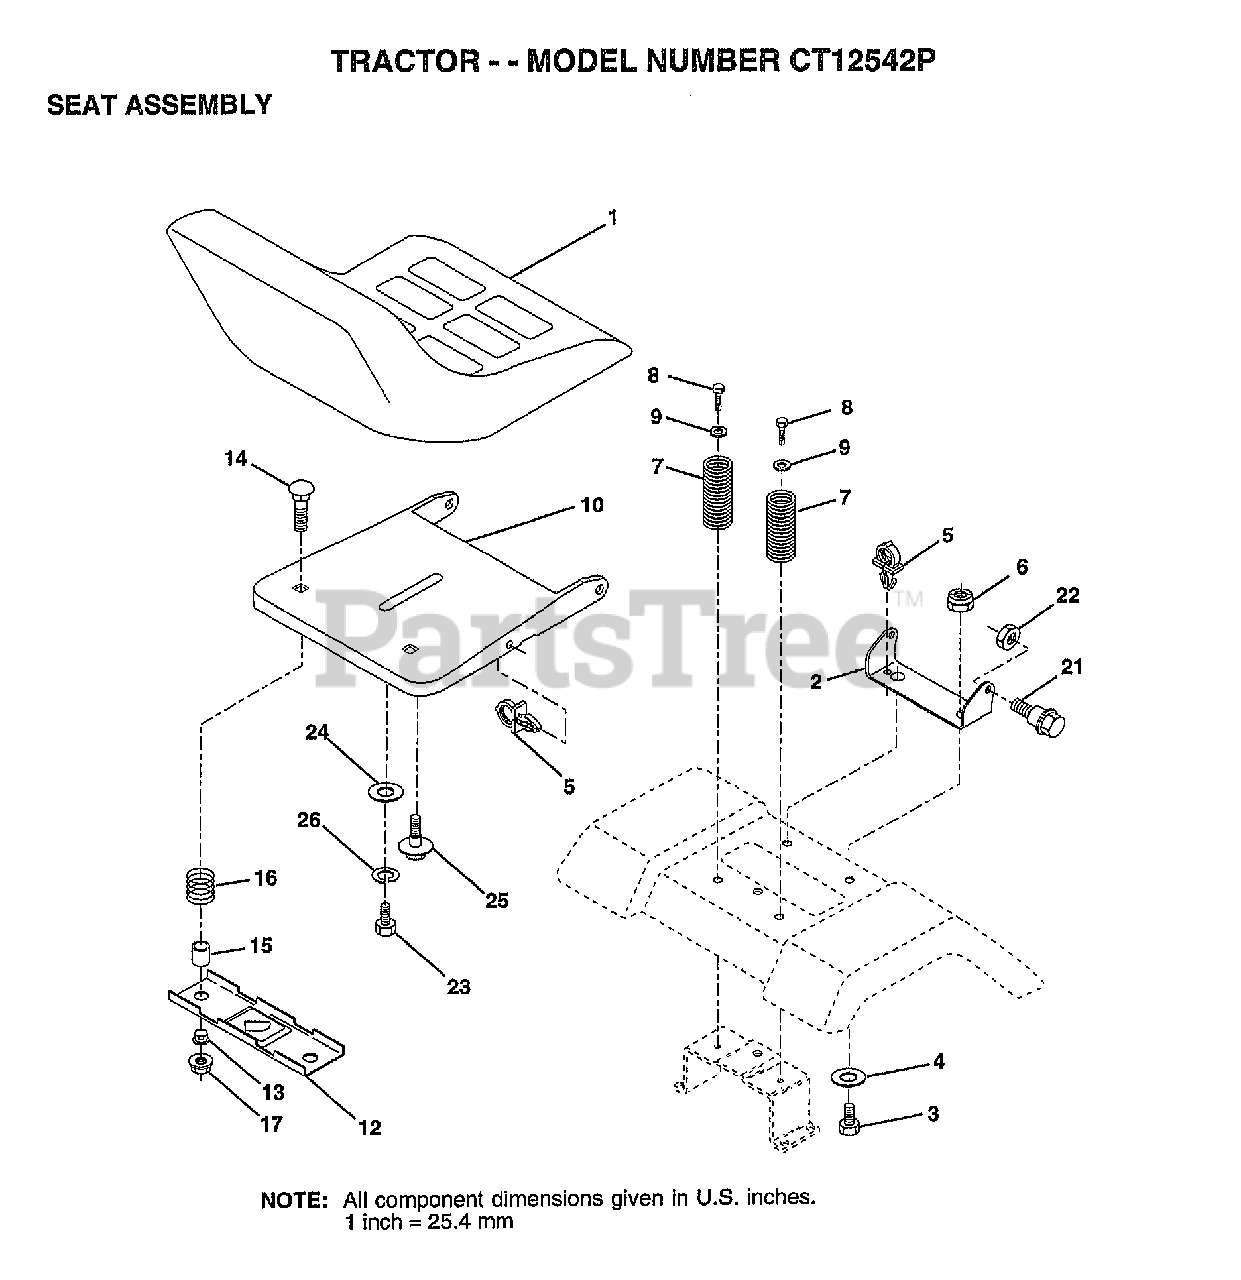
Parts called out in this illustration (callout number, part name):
2	BRACKET PVT SEAT
3	BOLT
4	WASHER PM
5	CLIP.PUSH-IN.HING
6	NUT
7	SPRING COMPRESSIO
8	SCREW GTV
9	WASHER
10	PAN-SEAT
12	BRKT SWITCH
13	BUSHING
14	BOLT-RD HD SQ NK
15	SPLIT SPACER
16	SPRING
21	"BOLT,SHOULDER"
22	NUT
23	BOLT
24	WASHER
25	"BOLT,SHOULDER"
26	LOCKWASHER
